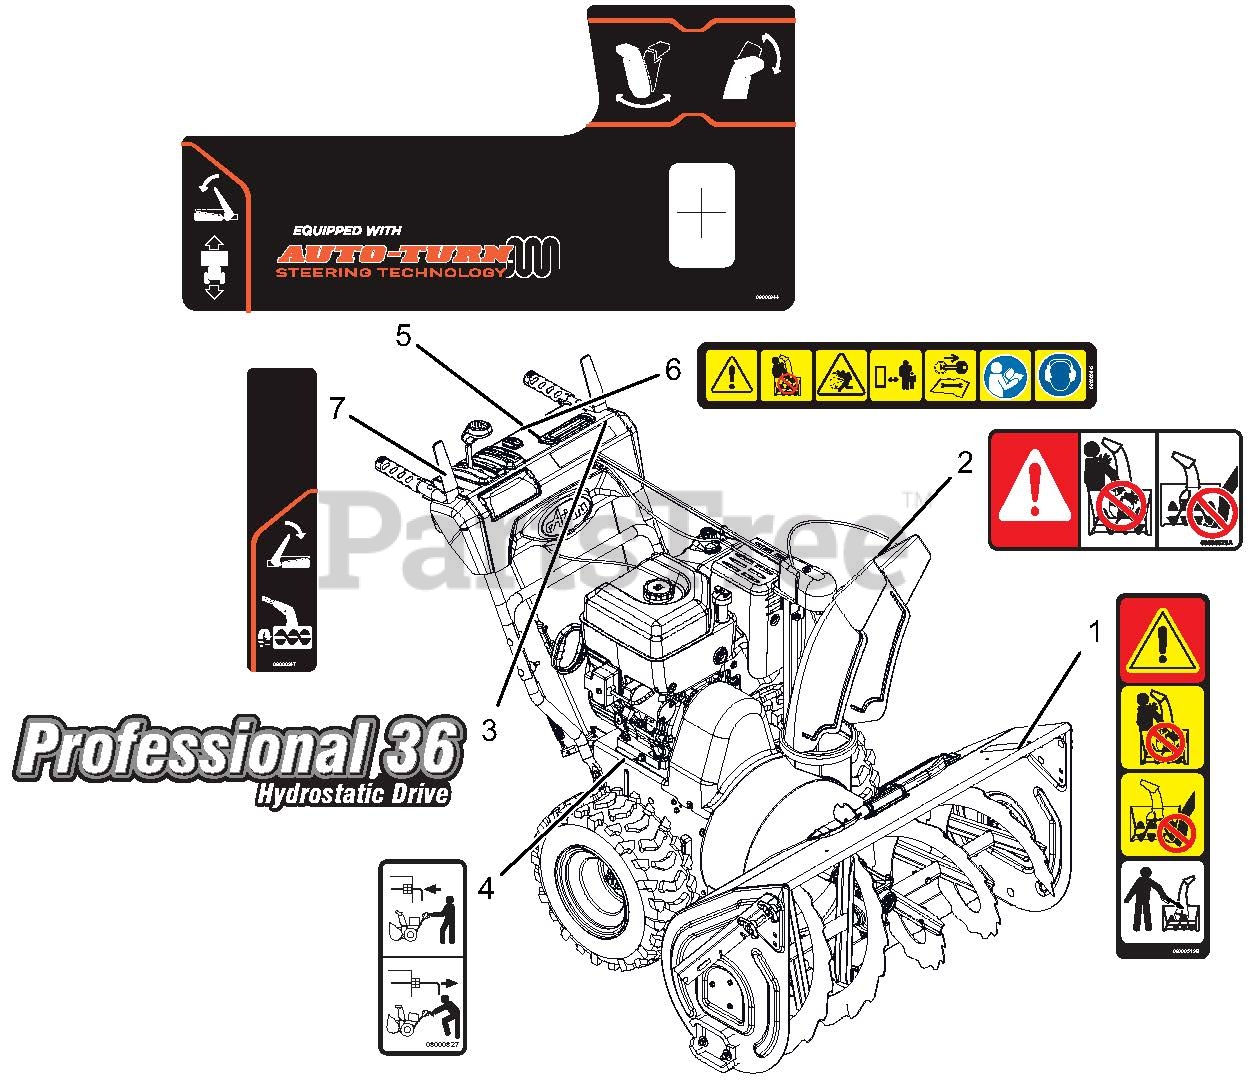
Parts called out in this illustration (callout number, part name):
1	DECAL, DANGER - ROTATING PARTS
2	DECAL, DANGER
3	DECAL, PRO HYDRO 36 DASH
4	DECAL, BYPASS
5	DECAL,CONTROL-LG QT2
6	DECAL,DASH - SAFETY
7	DECAL,CONTROL-RH CONTROL
